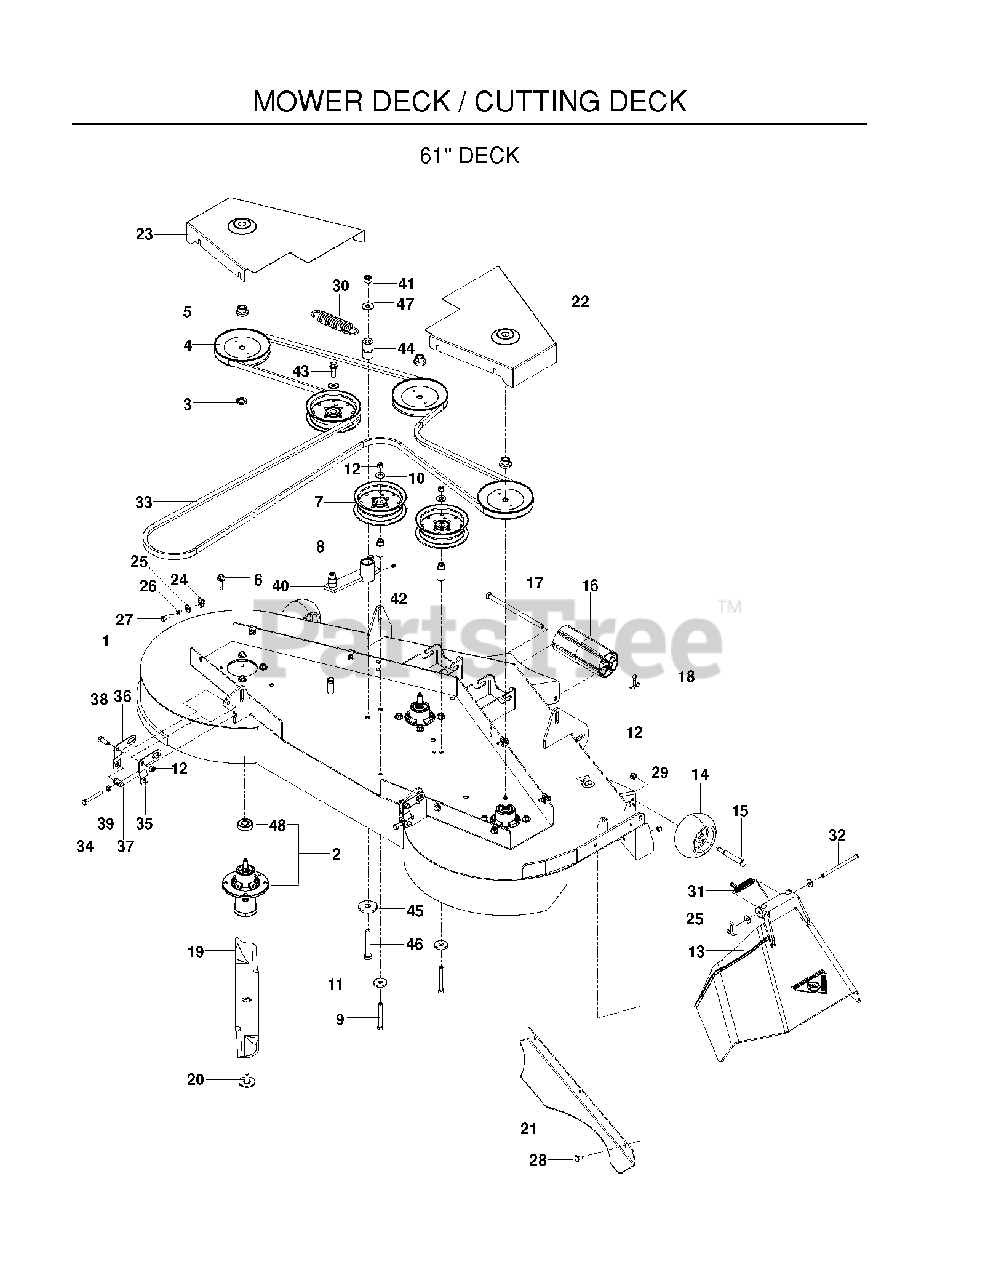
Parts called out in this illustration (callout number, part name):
1	DECK.FAB.W/DECALS.61".EZ.ORANG
2	MANDREL.DECK.ASSEMBLY
3	WASHER-SPACER
5	LOCKNUT - 9/16
6	WASHER HEAD SCREW
7	PULLEY, IDLER
8	IDLER BUSHING
9	HCS 3/8C X 3
10	RP WASHER 3/8 FLAT
11	SPINDLE WASHER
12	NUT 3/8-16 NYLOC
13	DISCHARGE CHUTE 61"
14	GAUGE WHEEL
15	SHOULDER BOLT 1/2X2-5/8 ZD SPE
16	NOSE ROLLER 48"
17	ROD.ROLLER.NOSE.NARROW.48"
18	RP_COTTER PIN 1/8 X 3/4
19	BLADE, 21"
20	BLADE BOLT ASSY-7/16" TB REPL
21	CONFINEMENT PLATE 61
22	BELT SHIELD, RH ORANGE
23	BELT.SHIELD.LH.ORANGE
24	U-CLIP 5/16-18 NUT RETAINER
25	WASHER 5/16 FLAT
26	WASH 5/16 DISC SPRING ZD
27	HCS 5/16C X 3/4
28	CARRIAGE BOLT 5/16C X 5/8"
29	NUT 5/16 NYLOC
31	SPRING - TORSION
32	PIN-CLEVIS 5/16 DIA X 5.19 ZD
33	BELT, DECK
34	HCS 5/16-18 X 2 1/2 TPBLT
35	PITCH, ADJUST, RT
36	PITCH, ADJUST, LT
37	TRUNION, PITCH
38	HCS 3/8-16X1.GRD.5.ZD
39	NUT 5/16C HEX
41	RP NUT 1/2-13 HEX NYLOC ZD
42	ZERK
43	4CS 3/8C X 1 SERRATED HEAD
44	PIVOT BUSHING
45	WASHER, SUPPORT
46	HCS 1/2C X 3 1/4
47	WASHER 1/2 FLAT
48	BEARING, BALL
